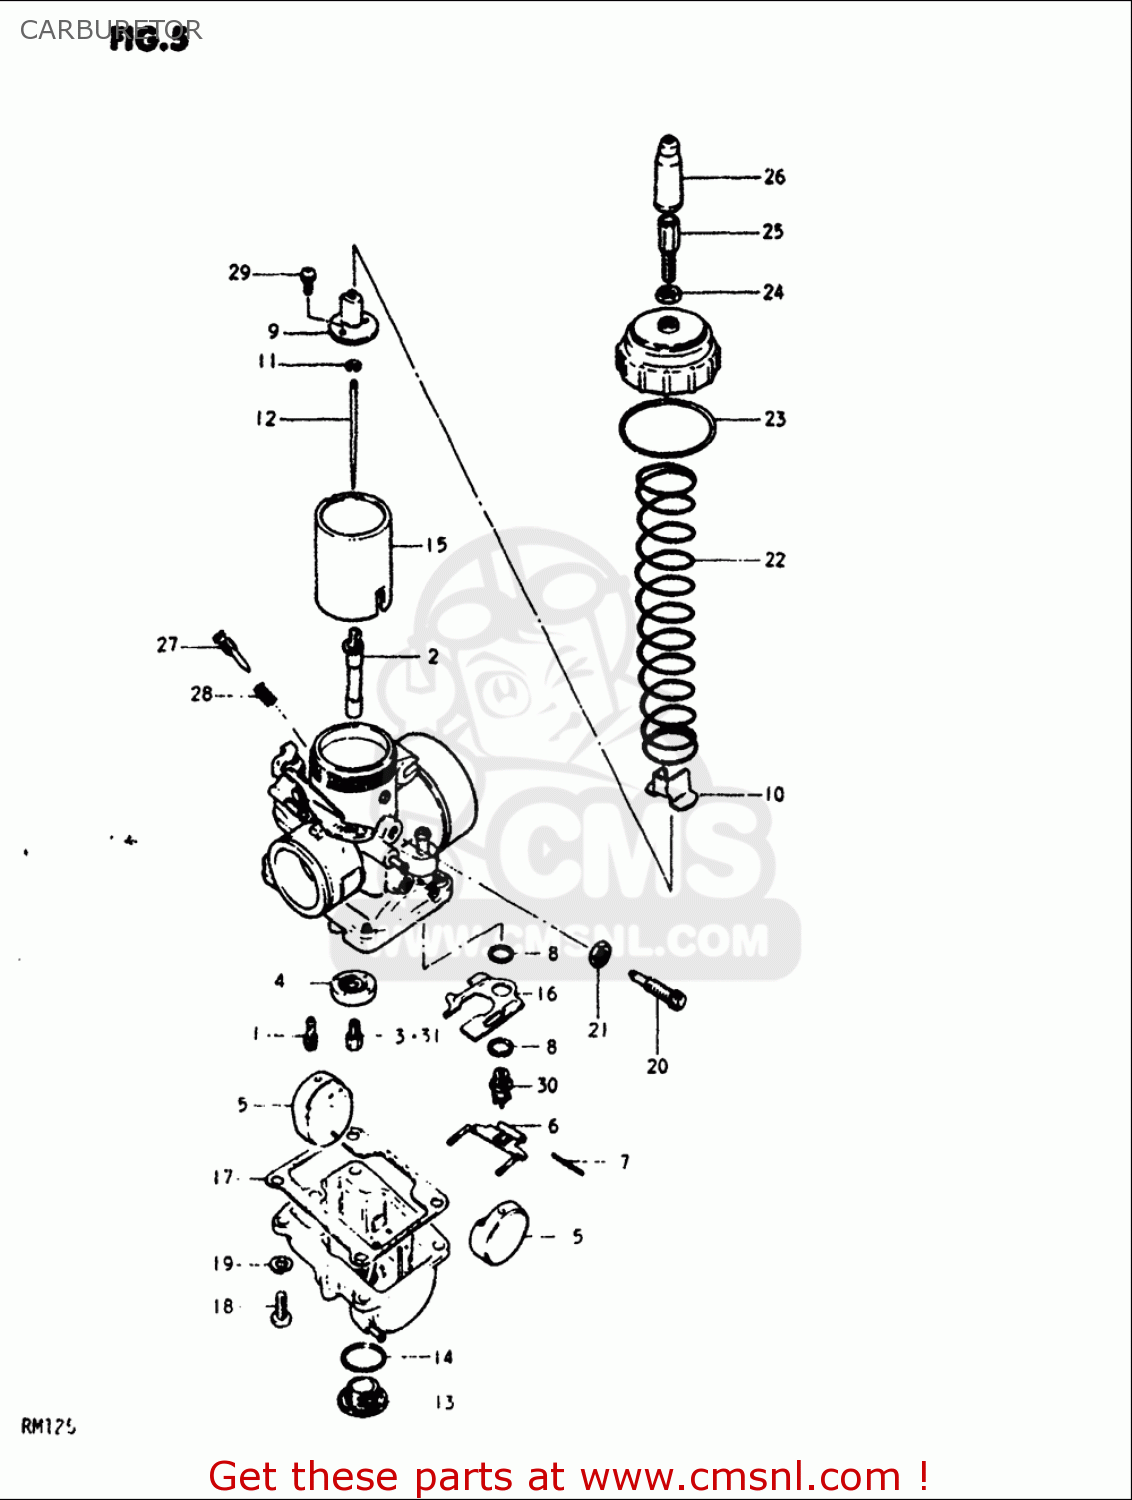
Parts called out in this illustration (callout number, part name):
1	JET,PILOT(25)
3	JET,MAIN(250)
5	FLOAT
6	ARM,FLOAT
7	PIN,FLOAT
8	GASKET,MAIN JET HOLDER (NAS)
9	CONNECTOR
10	COVER,HOLDER
11	CLIP
12	NEEDLE,JET
13	PLUG
14	O RING,DRAIN PLUG
17	GASKET,FLOAT CAHMBER (NAS)
18	SCREW
19	WASHER,LOCK
20	SCREW,THROTTLE STOP
21	NUT
22	SPRING,THROTTLE VALVE RETURN
24	NUT
25	ADJUSTER,CABLE
26	CAP
27	SCREW,PILOT AIR
28	SPRING
29	SCREW
30	VALVE ASSY,NEEDLE
31	JET,MAIN(240)
